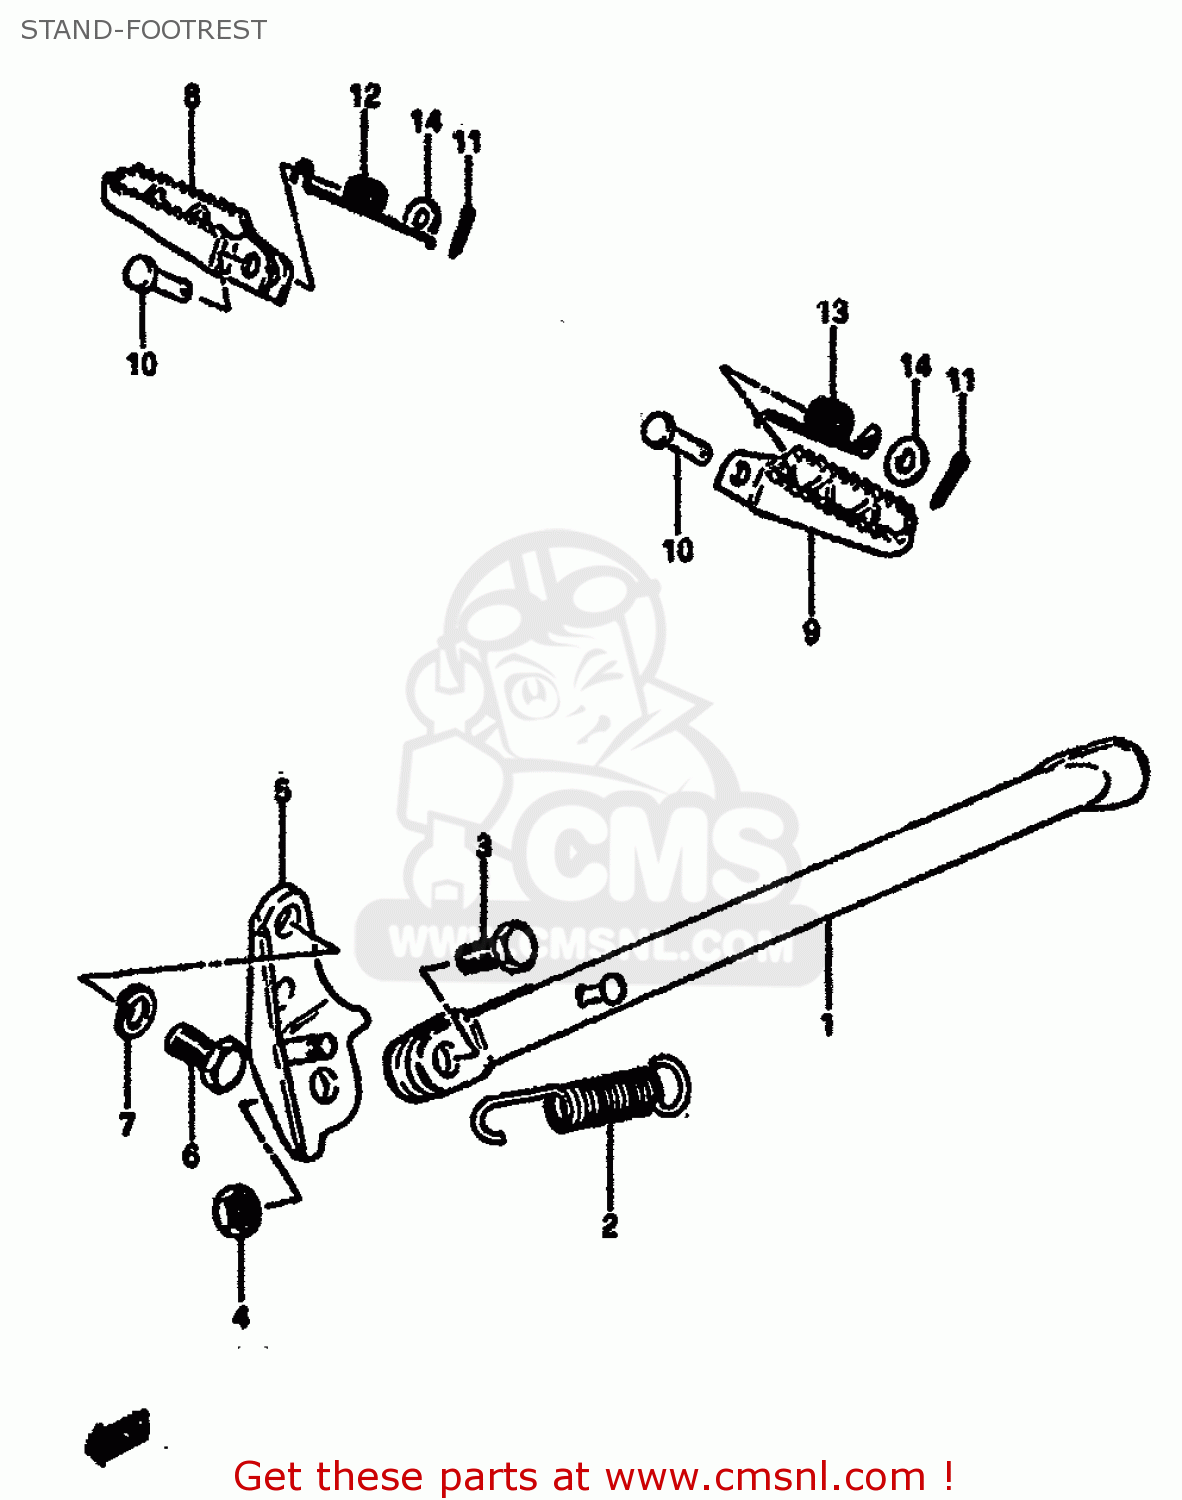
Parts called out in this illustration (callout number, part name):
1	STAND,SIDE
2	SPRING
3	BOLT(10X30)
4	NUT
5	BRACKET,SIDE STAND
6	BOLT(10X19)
7	LOCK WASHER
8	FOOTREST
9	FOOTREST
10	PIN
11	PIN 20X20
12	SPRING
13	SPRING
14	WASHER
